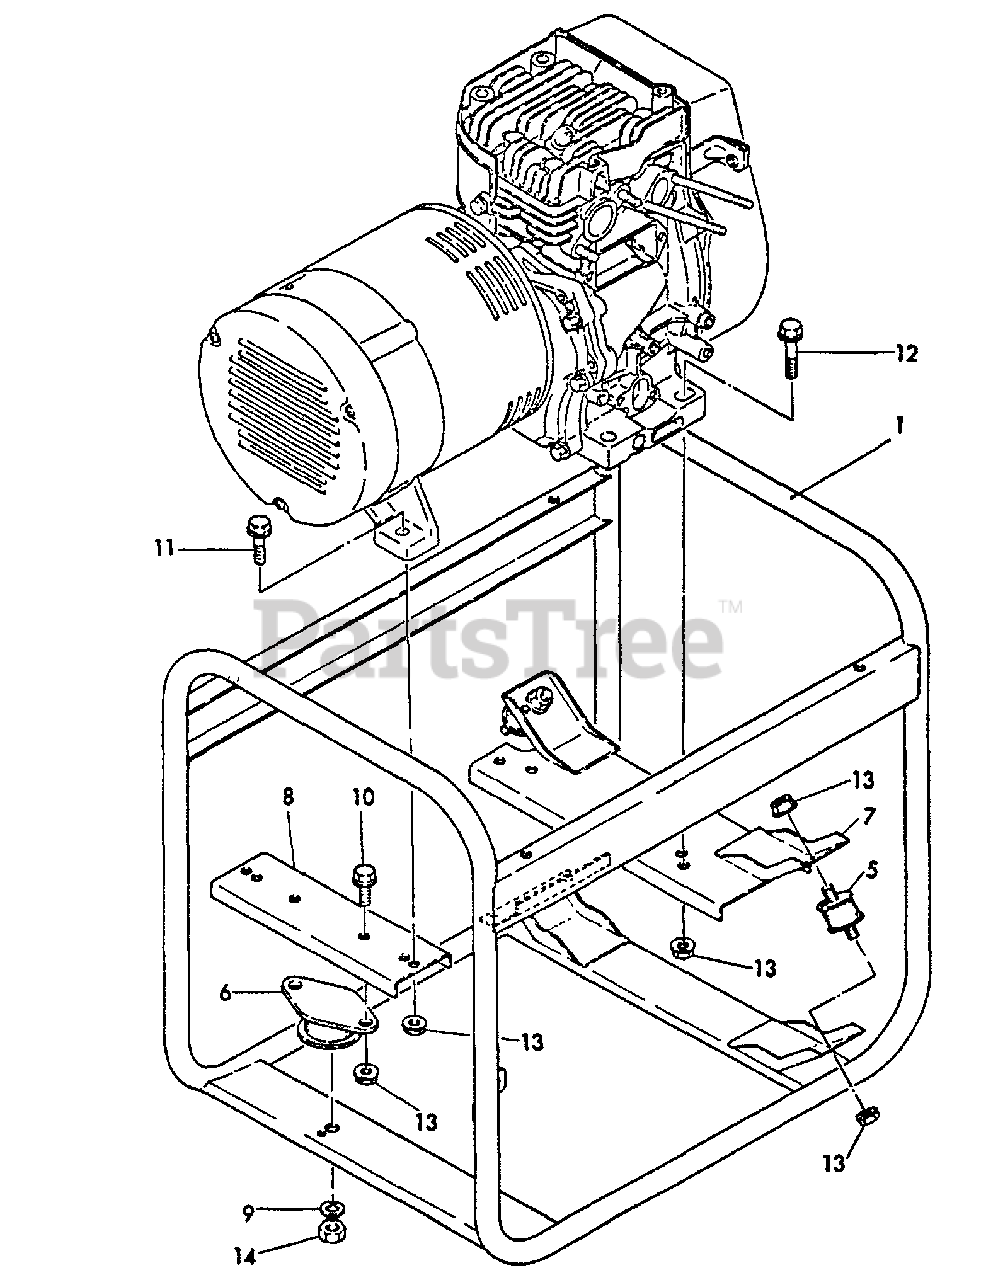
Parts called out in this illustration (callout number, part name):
1	FRAME ASSY
5	DAMPER, FRONT
6	DAMPER, REAR
7	STAY, DAMPER
8	STAY, REAR DAMPER
9	LOCKWASHER - 10
10	BOLT - 8×20 -- PLATED
11	BOLT - 8×30 -- PLATED
12	BOLT - 8×38 -- PLATED
13	U-NUT M8
14	NUT - 10
